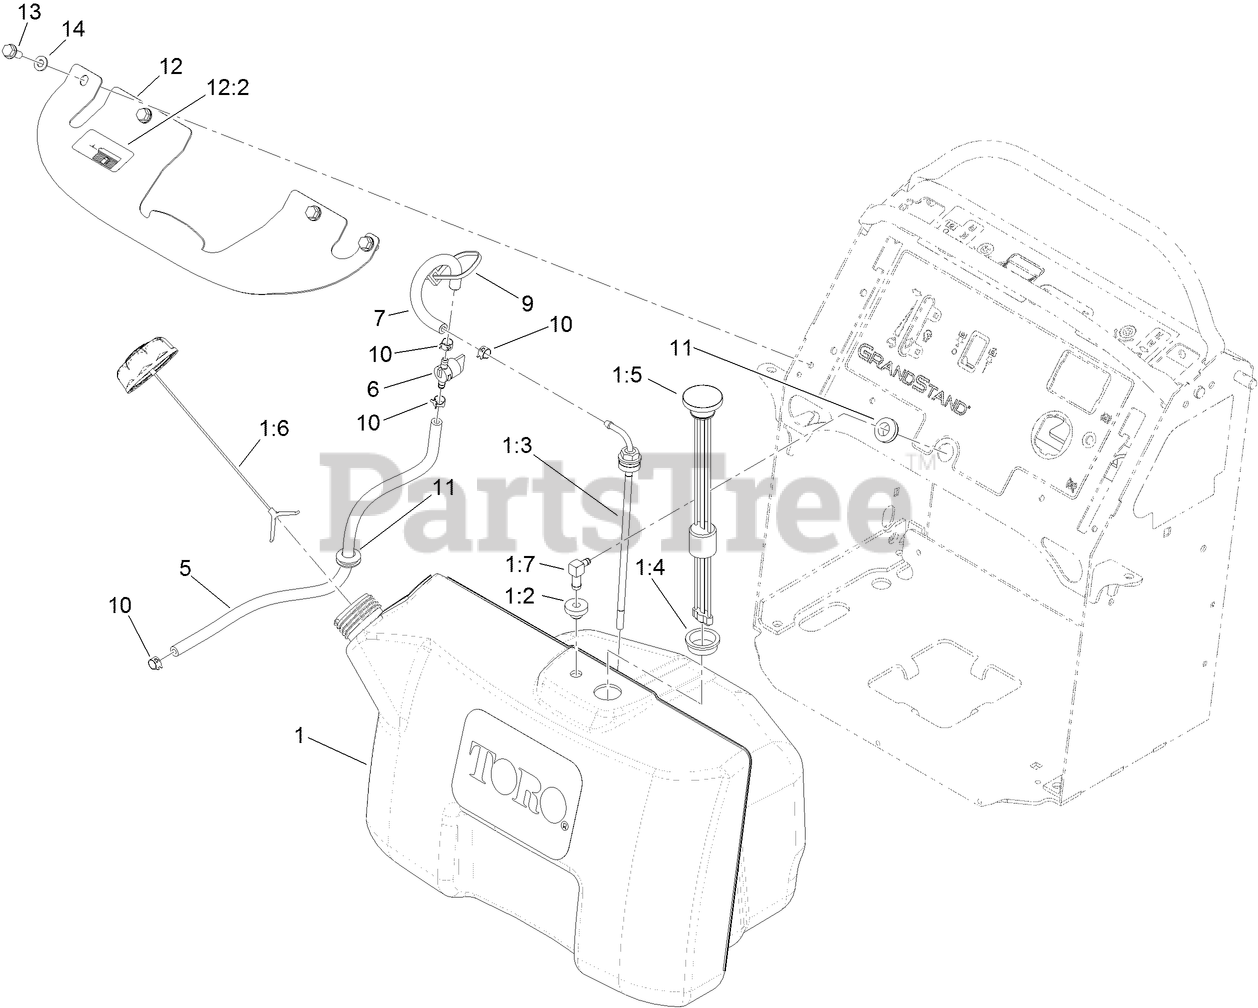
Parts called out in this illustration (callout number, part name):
1	TANK ASM
1:2	BUSHING
1:3	ELBOW-90 DEG
1:4	GROMMET
1:5	GUAGE-FUEL
1:6	CAP-FUEL, RATCHETING
1:7	FITTING-FUEL, BULKHEAD
5	HOSE-FUEL
6	VALVE-FUEL
7	HOSE-FUEL
9	TIE-CABLE
10	CLAMP-HOSE
11	GROMMET
12	BRACKET-TANK
12:2	DECAL-FILL, FUEL
13	SCREW-HWHTF
14	WASHER-FLAT
